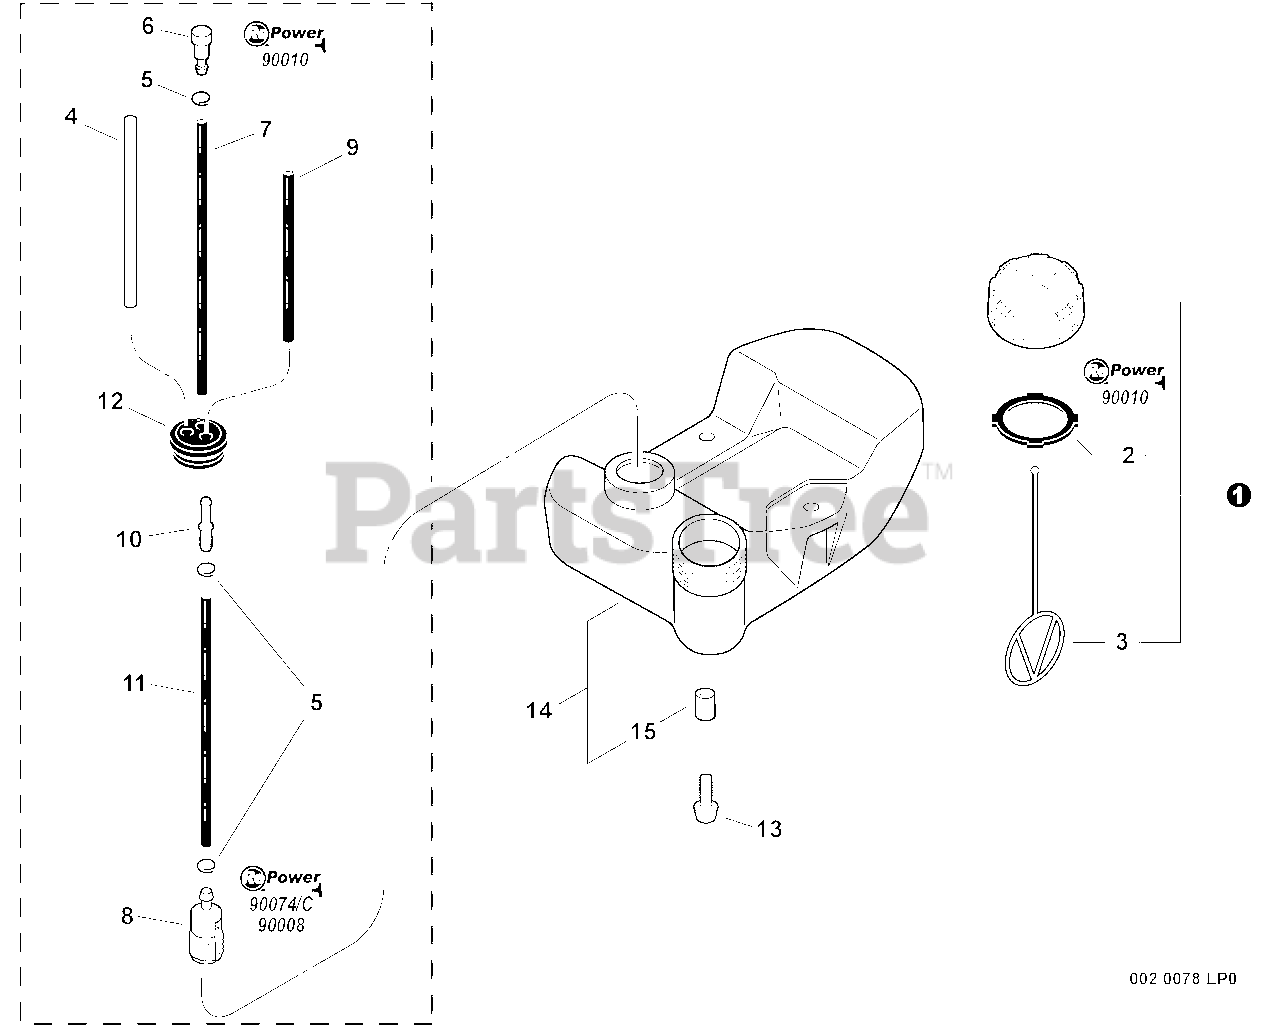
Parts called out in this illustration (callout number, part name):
1	CAP ASSY - ORANGE
2	GASKET, CAP
3	CONNECTOR, CAP
4	PIPE - 3X6X80 -- CLEAR
5	CLIP - 6.5
6	VENT, FUEL TANK
7	PIPE - 3X6X115 -- BLACK
8	FILTER, FUEL
9	PIPE - 3X5X67 -- BLACK
10	CONNECTOR, PIPE
11	PIPE - 3X6X110 -- BLACK
12	GROMMET
13	SCREW - 5X16
14	FUEL TANK ASSY
16	RePower TUNE-UP KIT
17	RePower FILTER KIT
18	Repower CAP AND VENT KIT
